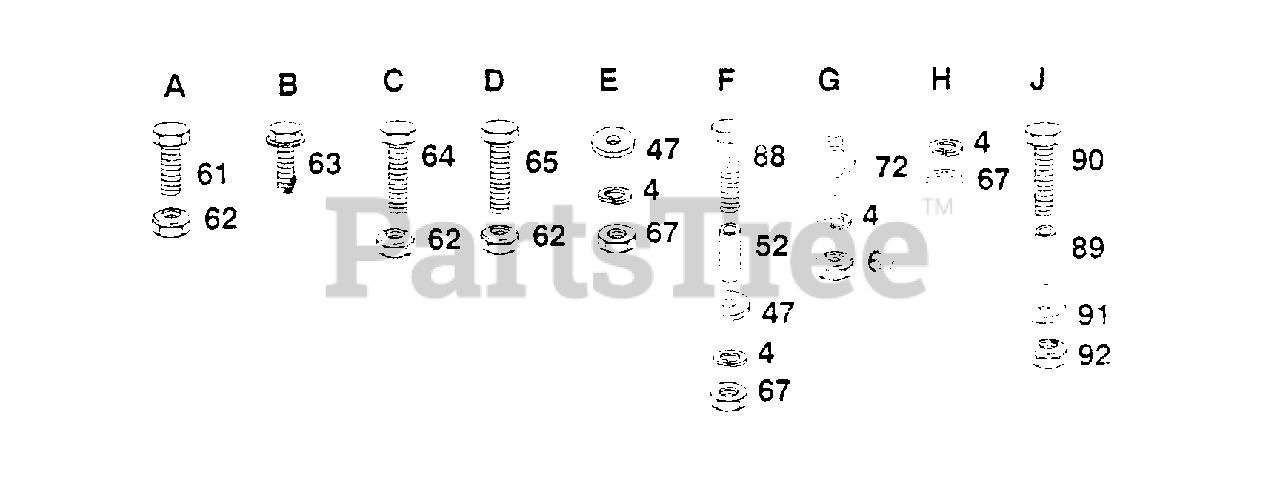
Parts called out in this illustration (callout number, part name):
4	Washer, Lock 3/8
6	Wheel, Steering
47	Washer 13/32 x 7/8 x 13 Gauge
52	Spacer, Split
61	Bolt, Hex 3/8-16 x 3/4
62	Locknut 3/8-16
63	Screw, Hex Wsh. Thdrol. 3/8-16 x 3/4
64	Bolt, Hex 3/8-16 x 1 Grade 5
65	Bolt, Hex 3/8-16 x 1
67	Nut, Hex 3/8-16
72	Pin Mounting, Idler, Bracket
88	Bolt, Hex 3/8-16 x 2-1/4
89	Bushing, Handle
90	Bolt, Hex 5/16-18 x 1
91	Washer 11/32 x 7/8 x 16 Gauge
92	Locknut 5/16-18
